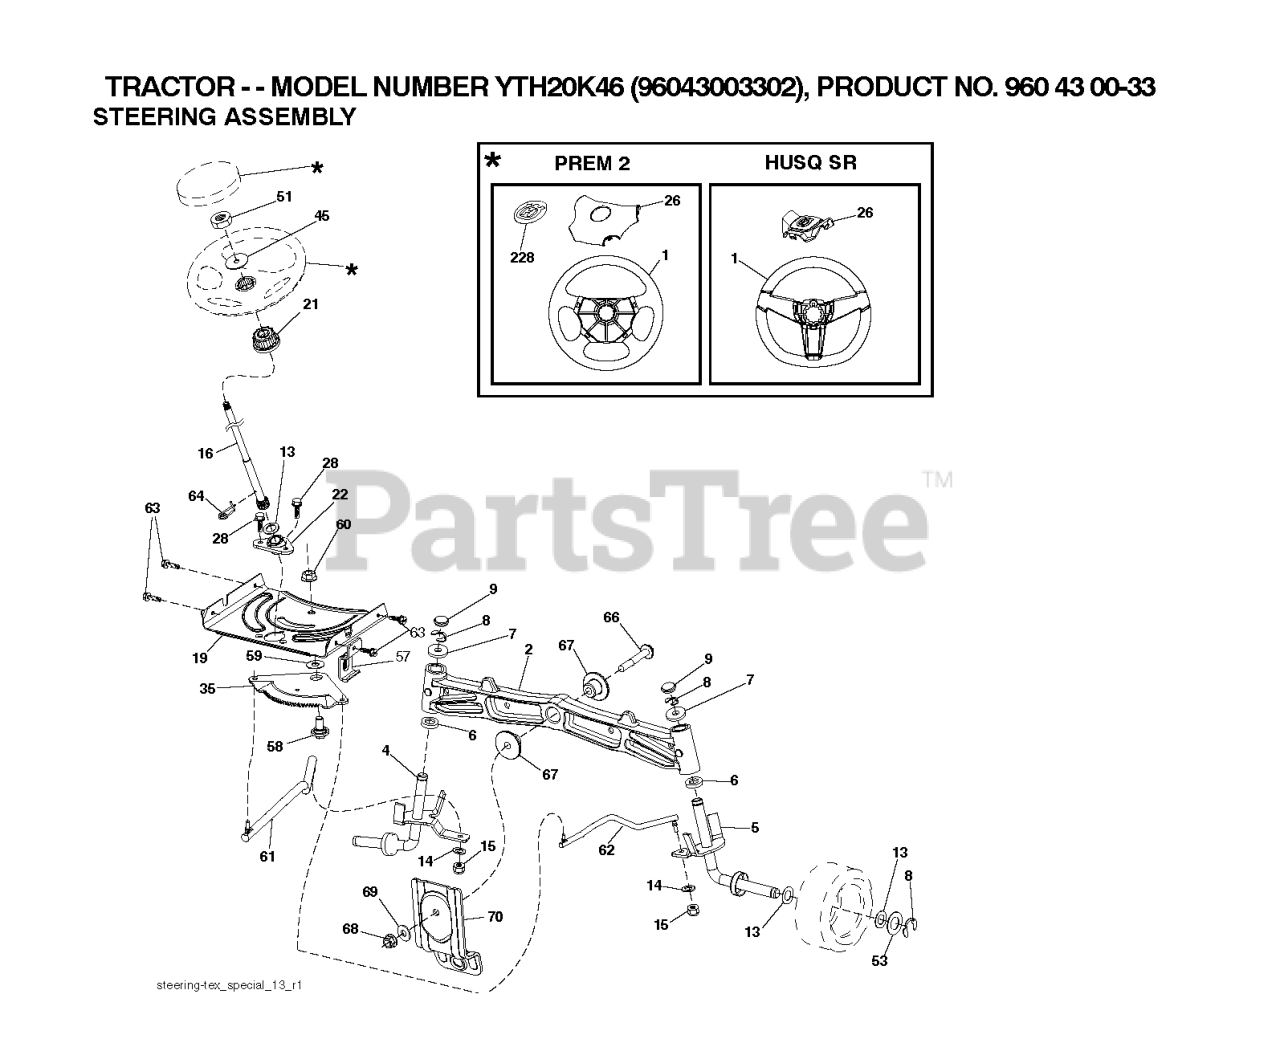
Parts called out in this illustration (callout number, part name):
2	AXLE.CAST.IRON
4	SPINDLE.WELDED.LH.15"TEX
5	SPINDLE.WELDED.RH.15"T
6	THRUST WASHER
9	CAP.SPINDLE.BLACK
14	WASHER, LOCK 3/8
15	NUT CROWNLOCK 3/8-24
16	SHAFT, STEERING
19	PLATE.STEER.DDL.NLT/NG
21	ADAPTER, WHEEL STNG..
22	BUSHING.ASM.STEERING.A
26	RP INSERT.CAP.WHL.STRG.HUSQ.
28	SCREW, 3/8-16X3/4
35	GEAR.SECTOR.PLATE.DDL.
45	WASHER 9/16"ID, 2 3/8"OD
51	NUT.HEX.1/2-20
53	WASHER.HARDENED
57	BRACKET.UPSTOP.TEX
58	BOLT.SHOULDER.SECTOR.P
59	WASHER.THURST.SECTOR.S
60	NUT FLANGE LOCK 5/8-11
61	DRAGLINK.LH.BALLSTUD.D
62	DRAGLINK.RH.BALLSTUD.D
63	SCREW
64	RETAINER.CLIP.SPRING.S
66	BOLT HEX FGHD 7/16-14 X 3 SERR
67	BUSHING.PM.FRONT AXLE
68	NUT.LOCK.FLANGE.7/16
69	WASHER.1.5X.505X.118
70	BRKT.DECK.SUSPENSION.F
